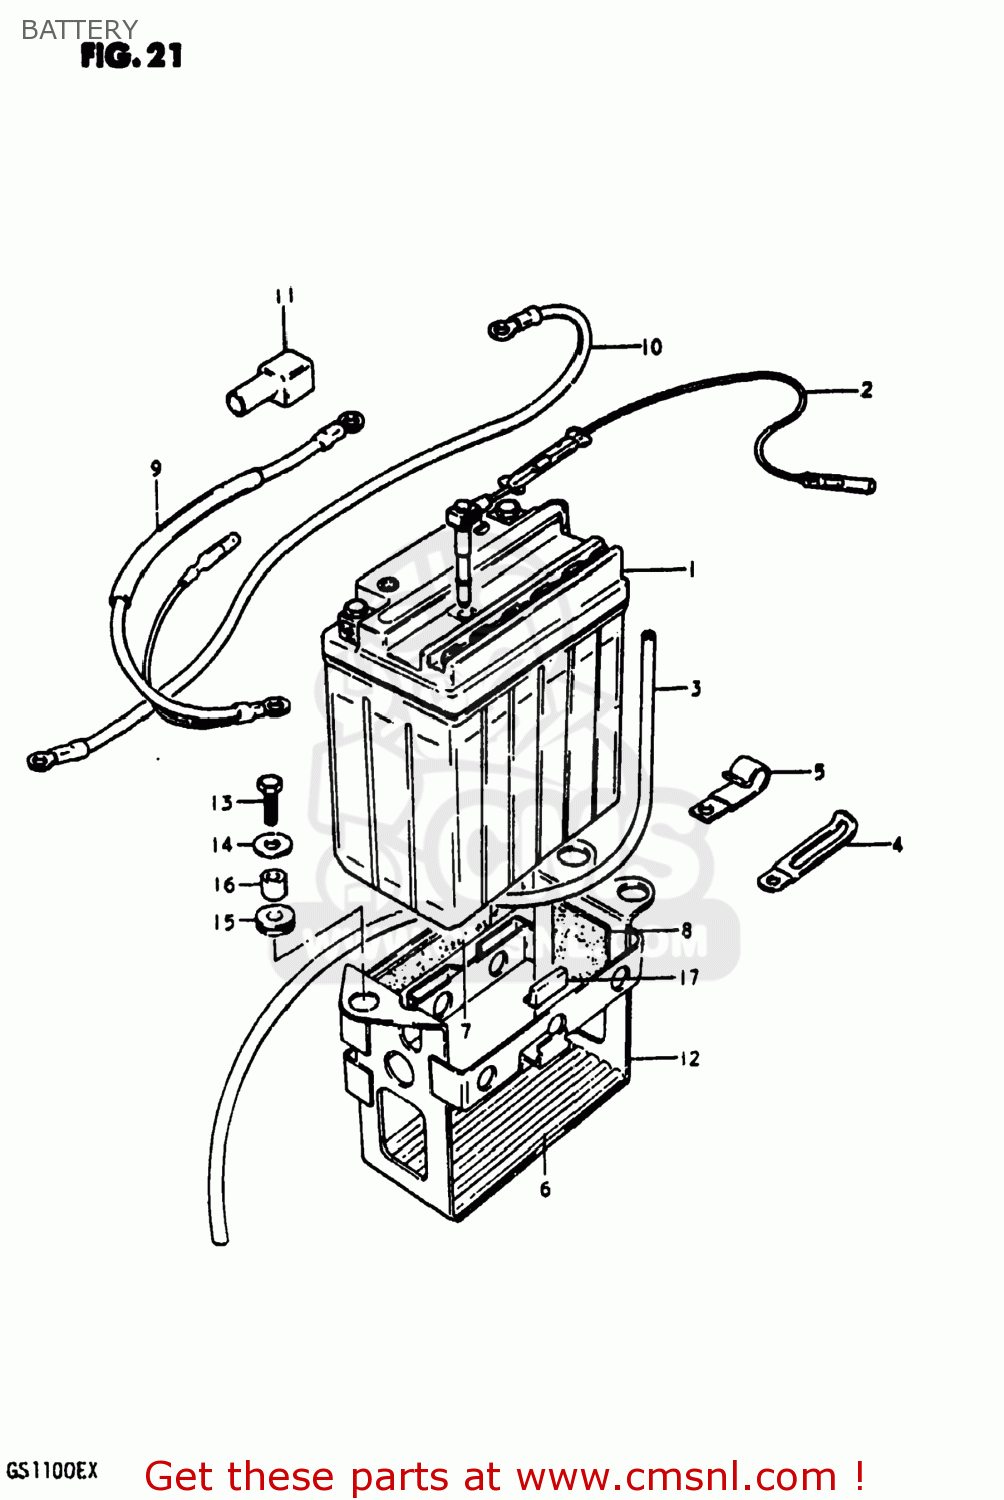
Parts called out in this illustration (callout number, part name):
1	BATTERY ASSEMBLY (12V)
2	SENSOR,BATTERY LEVEL
3	HOSE,BATTERY EXHAUST
4	CLAMP L:35
5	CLAMP
6	PROTECTOR,BATTERY
7	PROTECTOR(20X90)X4
8	PROTECTOR,BATTERY
9	WIRE,BATTERY PLUS
10	LEAD WIRE,BATTERY(-)
11	CAP,TERMINAL
12	HOLDER,BATTERY
13	BOLT, UPPER
14	WASHER
15	CUSHION
16	SPACER(6.1X9X7.5)
17	CUSHION,FRAME COVER
